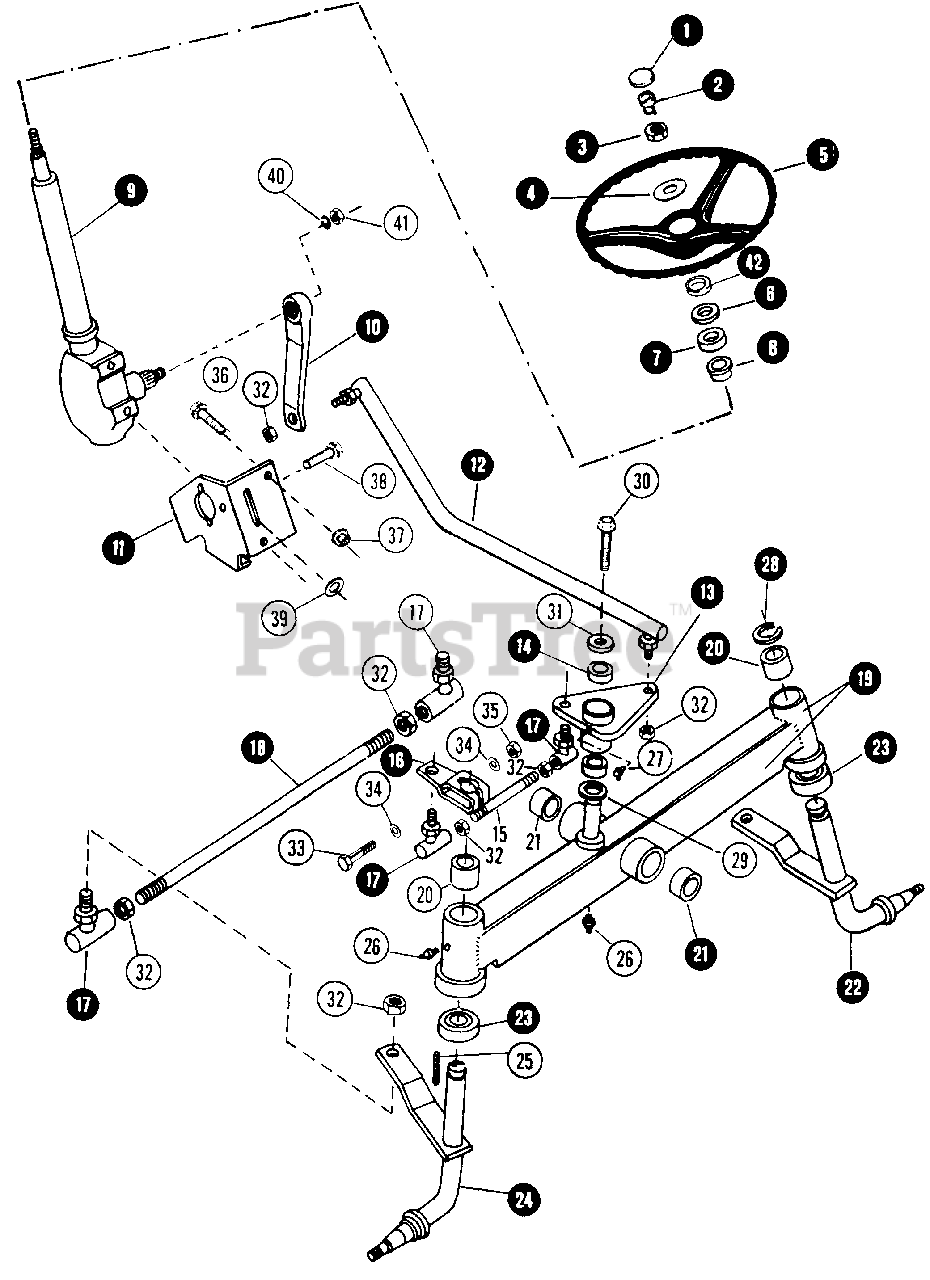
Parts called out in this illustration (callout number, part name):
1	PLATE, SNAPPER EMBLEM
2	TAPER - PLUG
3	NUT, 5/8 NF HEX
4	WASHER, 5/8 FLAT
5	WHEEL, STEERING
6	COVER, DUST
7	CAP, STEERING COLUMN
8	BEARING, STEERING
9	STEERING GEAR-ASSEMBLY
10	ARM, STEERING PITMAN
11	BRACKET GEAR MOUNTING
12	LINK, DRAG
13	ARM, LEVER - ASSEMBLY
14	BUSHING, LEVER ARM
15	TIE-ROD STEERING
16	ARM, STEERING
17	BALL-JOINT, STEERING
18	TIE-ROD, STEERING
19	FRONT-AXLE ASSEMBLY
20	BUSHING, SPINDLE
21	BUSHING, AXLE
22	SPINDLE, LEFT AXLE
23	BEARING, SPINDLE BALL
24	SPINDLE, RIGHT AXLE
25	KEY, 1/4 SQUARE x 1-1/4
26	FITTING, Lube (Press fit for .187 hole-no ball)
27	FITTING, GREASE DRIVE-IN
28	RING, SPINDLE RETAINING
29	WASHER, LEVER ARM THRUST
30	BOLT, 3/8C x 3/4 HEX FLANGE
31	WASHER, LEVER ARM
32	NUT, 1/2 NF HALF HEX
33	BOLT, 3/8C x 2-1/2 HEX HEAD
34	WASHER 3/8 FLAT
35	NUT, 3/8C HEX
36	BOLT, 3/8C x 1-1/4 HEX FLANGE
37	NUT, 3/8C HEX FLANGE
38	BOLT, 7/16C x 3/4 HEX FLANGE
39	WASHER, 13/32 x 1 x 1/8
40	WASHER, 5/8 LOCK
41	NUT, 5/8 NF HEX
42	SLEEVE, STEERING
